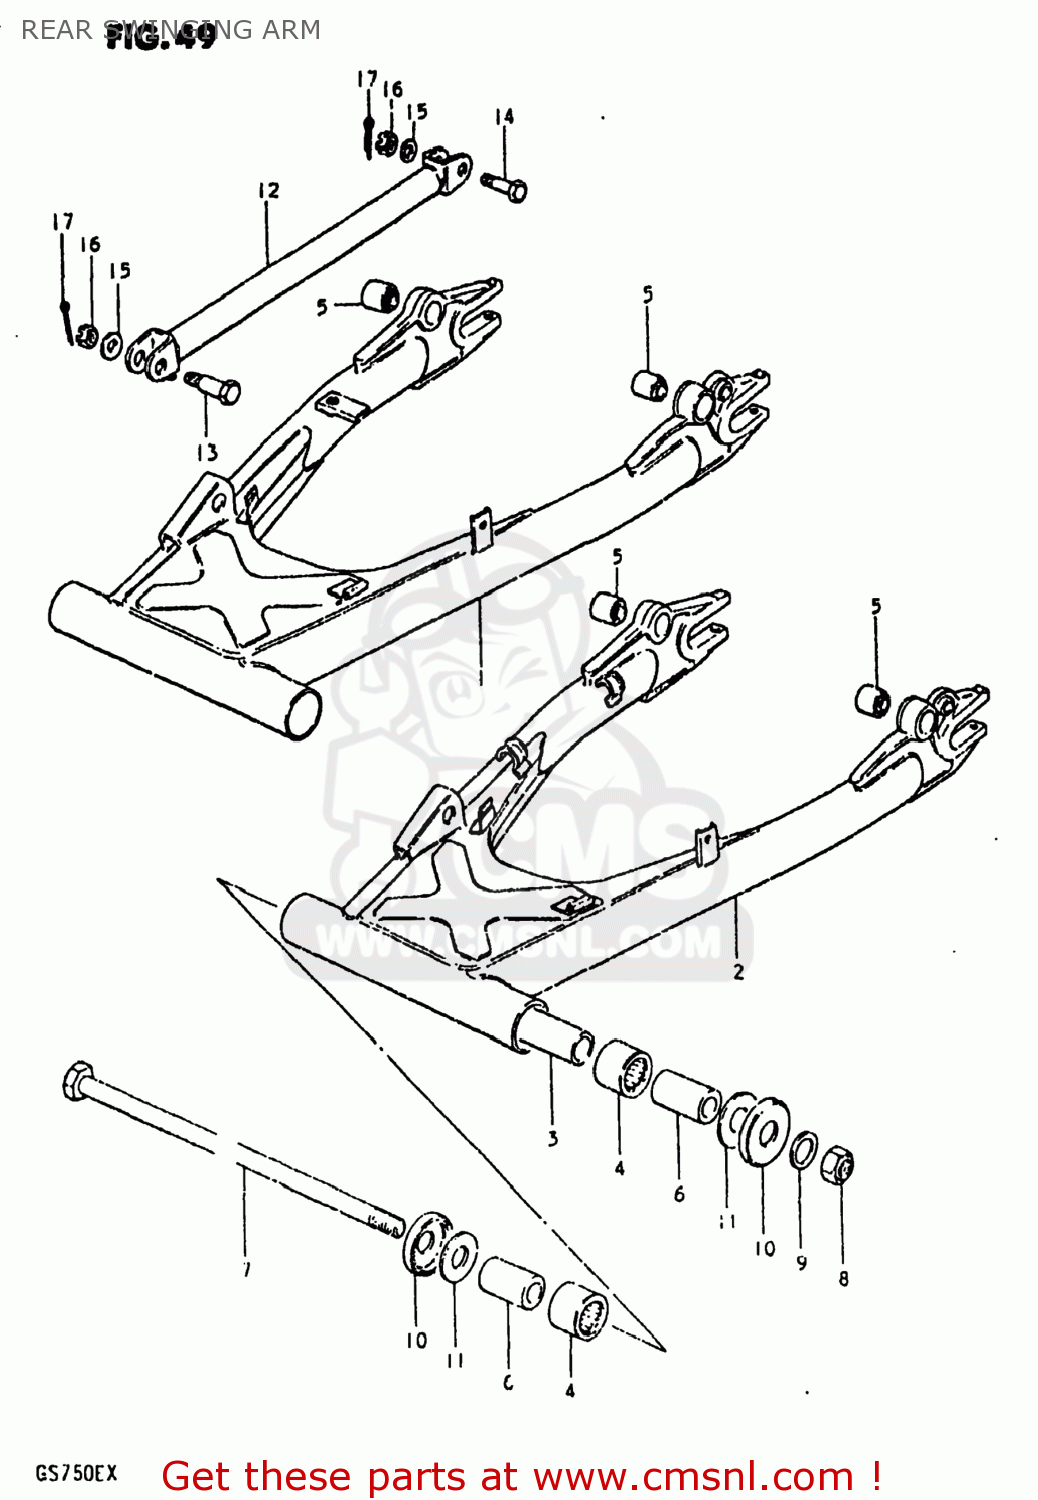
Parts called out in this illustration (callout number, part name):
1	SWING ARM ASSEMBLY,REAR
2	SWING ARM ASSEMBLY,REAR
3	SPACER,RR SWGARM PIVOT CTR
4	BEARING(22X29X30)
5	BUSH
6	SPACER,RR SWGARM PIVOT
7	SHAFT,REAR SWING ARM
8	NUT 14MM
9	WASHER
10	CVR,RR SWGARM DUST SEAL(OD:40)
11	WASHER(14.2X34X1)
12	LINK,REAR TORQUE
13	BOLT
14	BOLT(10X39)
15	WASHER
16	NUT
17	PIN 20X20
